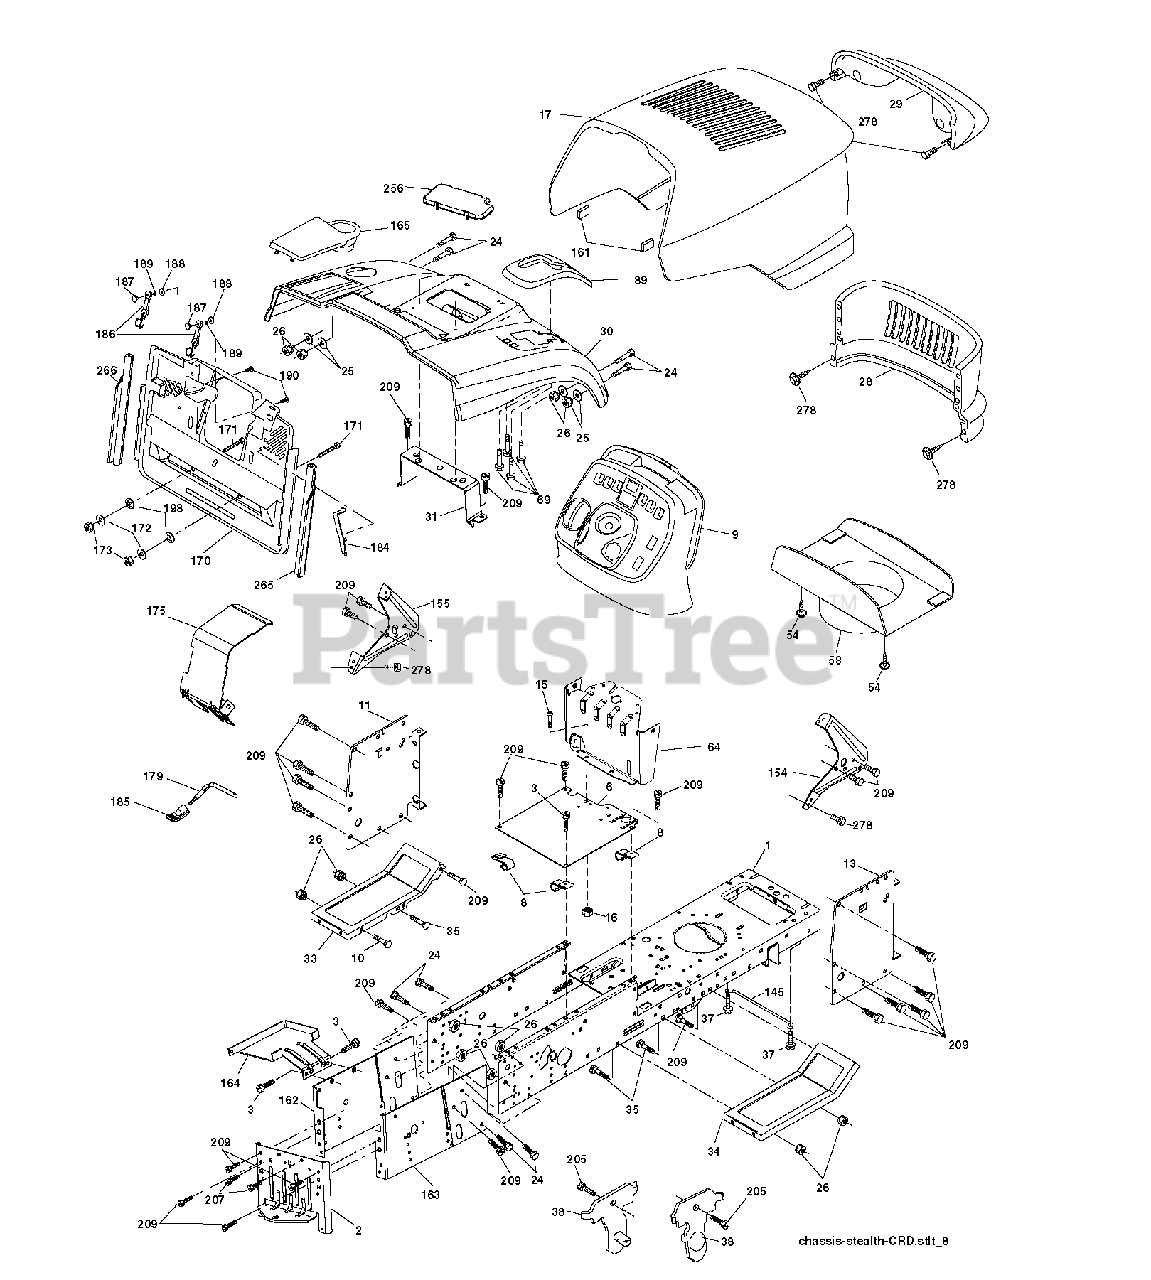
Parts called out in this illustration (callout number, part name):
1	CHASSIS
3	SCREW 3/8-16X3/4
8	CLIP,INSULATOR
10	BOLT D
13	PANEL DASH RH
16	NUT
24	BOLT
25	WASHER
26	NUT
31	BRACKET SUPPORT FENDER
35	BOLT
37	SCREW LT
54	SCREW.WSHD.HEX10-32X5/8
58	DUCT HOOD
69	SCREW.HI-LO.CONSOLE
145	ROD.PIVOT.HOOD
161	EXTRUSION BUMPER
164	SUPPORT
171	BOLT
172	WASHER
186	LATCH ASSY
187	WELDNUT
189	LOCKWASHER
190	SCREW
205	SCREW LT
207	SCREW, 5/16-18 X 1/2
209	SCREW, 3/8-16X3/4
278	SCREW.#10 X 0.750.BOS THREAD
